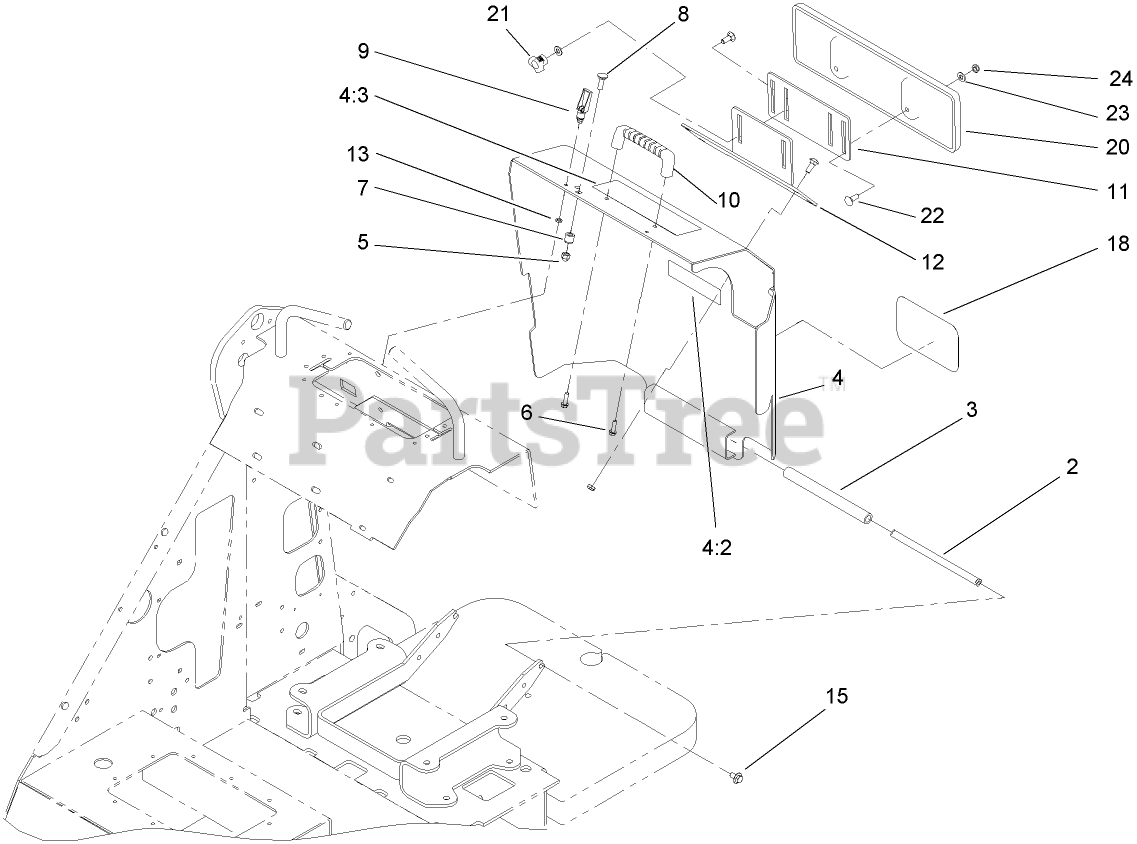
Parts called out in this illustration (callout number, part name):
2	BAR-HINGE
3	HOSE-HINGE
4	COVER ASM
4:2	DECAL-DANGER
4:3	DECAL-DANGER
5	NUT-LOCK, CAP
6	SCREW-HWH
7	SPACER-GUIDE
8	SCREW-CARR
9	LATCH-SWELL
10	HANDLE-DOOR
11	PLATE-ADJUSTING
12	BRACKET-SUPPORT, THIGH
13	WASHER
15	SCREW-HHF
18	DECAL
20	SUPPORT-THIGH
21	Knob-Adjustment
22	SCREW-CARR
23	WASHER-FLAT
24	NUT-LOCK, NI
